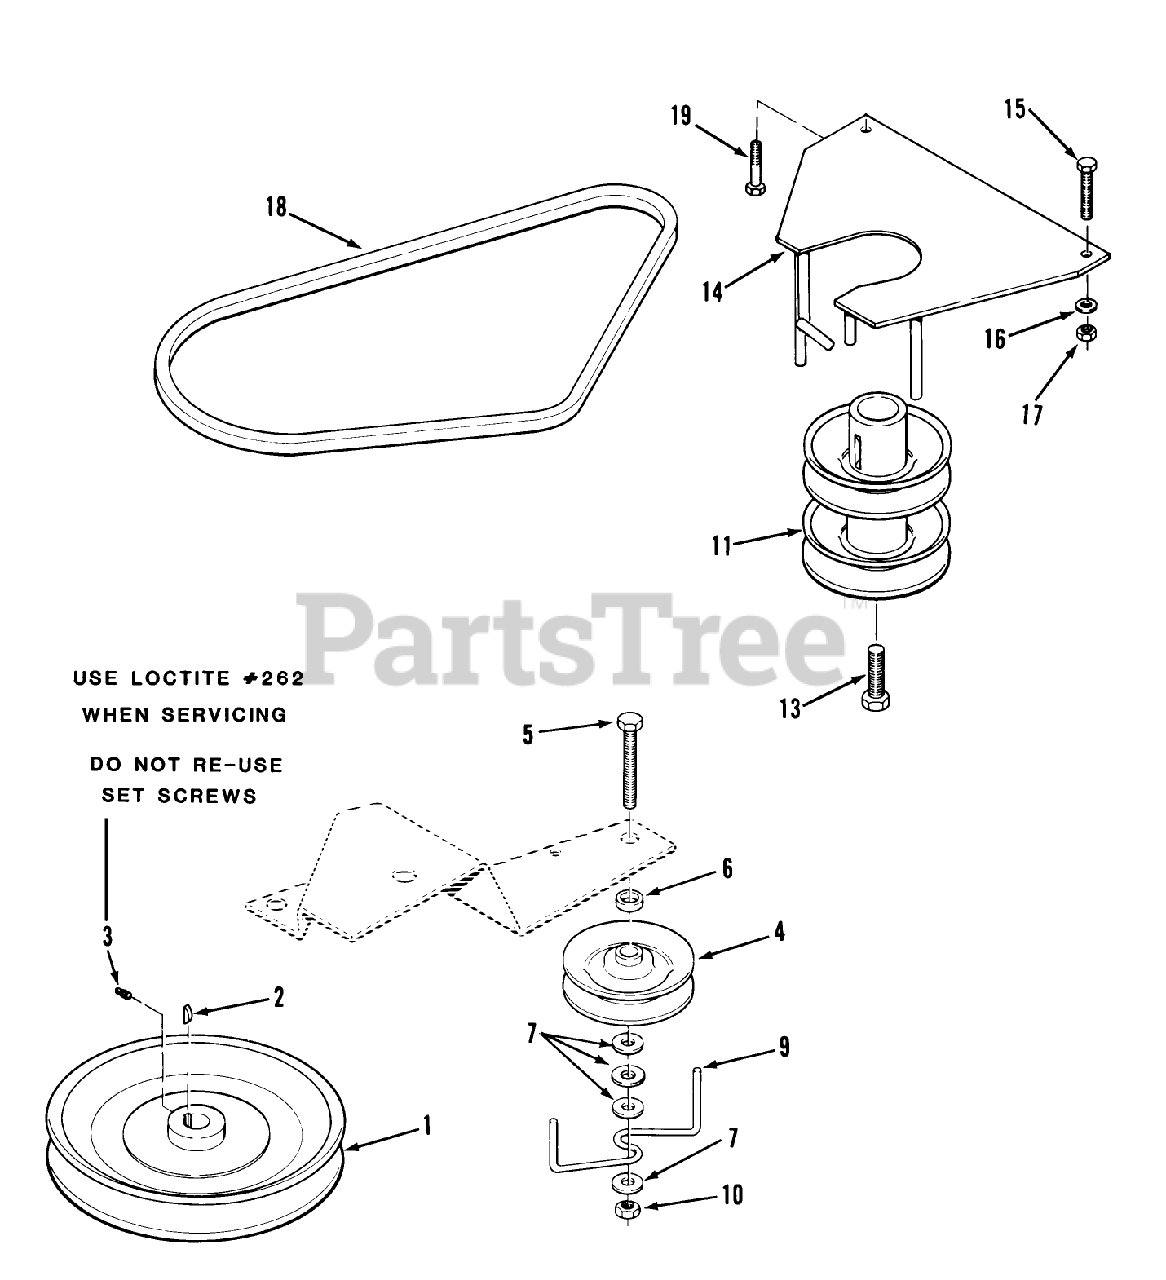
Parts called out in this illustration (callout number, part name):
1	PULLEY TRANSMISSION
2	KEY-HI-PRO
4	PULLEY-IDLER V
6	SPACER
9	GUIDE - BELT
10	NUT-HEX, JAM
11	PULLEY-ENGINE
13	HEX HD CAP SCREW
16	WASHER 5/16 SAE
18	BELT-V
